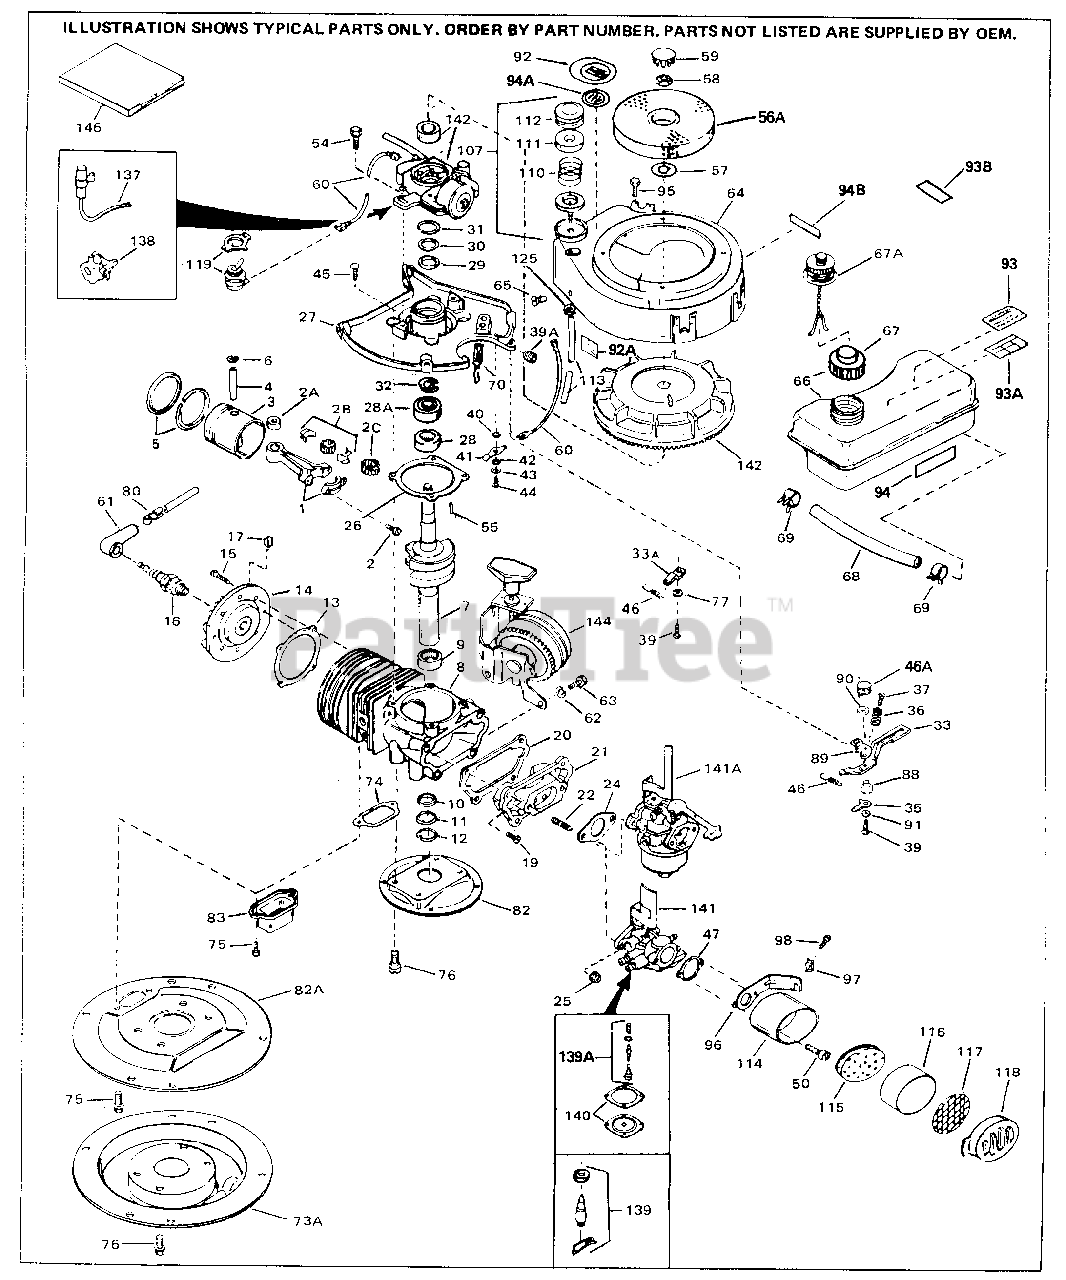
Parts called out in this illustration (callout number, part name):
1	"Rod Assy., Connecting Incl. 2, 2A & 2 B
2	Screw, Connecting rod
2A	Bearing, Cartridge
2B	Bearing & Liner Set, Needle 37 Needl es
3	Piston
4	Pin, Piston
5	Ring Set, Piston
6	Ring, Piston pin retaining
7	Crankshaft
8	Block Assy., Cylinder Incl. 9 thru 1 2
9	Bearing, Needle
10	Seal, Crankshaft
11	Retainer, Crankshaft seal
12	Spring, Crankshaft seal retainer
13	* Gasket, Cylinder head
14	CYL HEAD
15	Screw, Torx T-30, 1/4-20 x 3/4"
16	Resistor Spark Plug - RJ17LM
19	Screw, Torx T-25, 10-24 x 1/2"
20	* Gasket, Reed plate
21	Plate Assy., Reed (Incl. 22)
22	Stud, Carburetor
24	* Gasket, Carburetor
25	Nut, Hex, 1/4-20 (Use as required)
25	Nut, Hex, 1/4-28 (Use as required)
26	* Gasket, Housing base
27	Blower Housing Base
28	Bearing, Needle
29	Seal, Crankshaft
30	Retainer, Crankshaft seal
31	Spring, Crankshaft seal retainer
32	Ring, Retainer (Use as required)
33	Lever, Control
35	Lever, Adjusting
37	Screw, 5-40 x 7/16"
39	Screw, Torx T-25, 10-24 x 7/8"
45	Screw, Torx T-30, 1/4-20 x 5/8"
46	Spring, Governor
47	Gasket
50	Screw, Torx T-25, 10-32 x 5/8"
54	Screw, 1/4-20 x 3/4"
55	Key, Flywheel
58	Nut, Flywheel
60	Wire, Cut off
61	Cover, Spark plug
64	Blower Housing
65	Screw, 1/4-20 x 3/8"
66	Tank, Fuel (Incl. 67)
67A	Fuel Cap
68	Fuel Line (8.62")
68	Fuel Line (16") (Use as required)
69	Fuel Line Clamp
74	Gasket, Exhaust
75	Screw, 1/4-20 x 3/8"
83	Muffler
92A	Decal, Instruction
107	Primer Assy. (Incl. 110 thru 113)
110	Spring, Primer bulb (Use as required)
111	Washer, Primer bulb (Use as required)
112	Bulb, Primer
113	Line, Primer
114	Body, Air filter
115	Air Cleaner Screen
116	Air Filter
117	Air Filter
118	Cover, Air filter
119	Switch, Toggle
137	Condenser (also available in Packaged Part #740037B)
138	Breaker Points (also available in Pac kaged Part #740037B)
139A	Inlet Needle, Seat, Spring & Gasket A ssy.
140	Diaphragm & Gasket Assy.
141	Carburetor (Incl. 24, 139A & 140) (Re fer to Division 5, Section A, page 12 6 for breakdown)
142	Magneto NOTE: The complete magneto i s not available as an assembly. The magneto number is shown for reference purposes only. Order component part s individually, as shown in parts lis t. (Refer to Division 5, Section B, p age 28 for breakdown)
146	* Gasket Set (Incl. items marked *)
